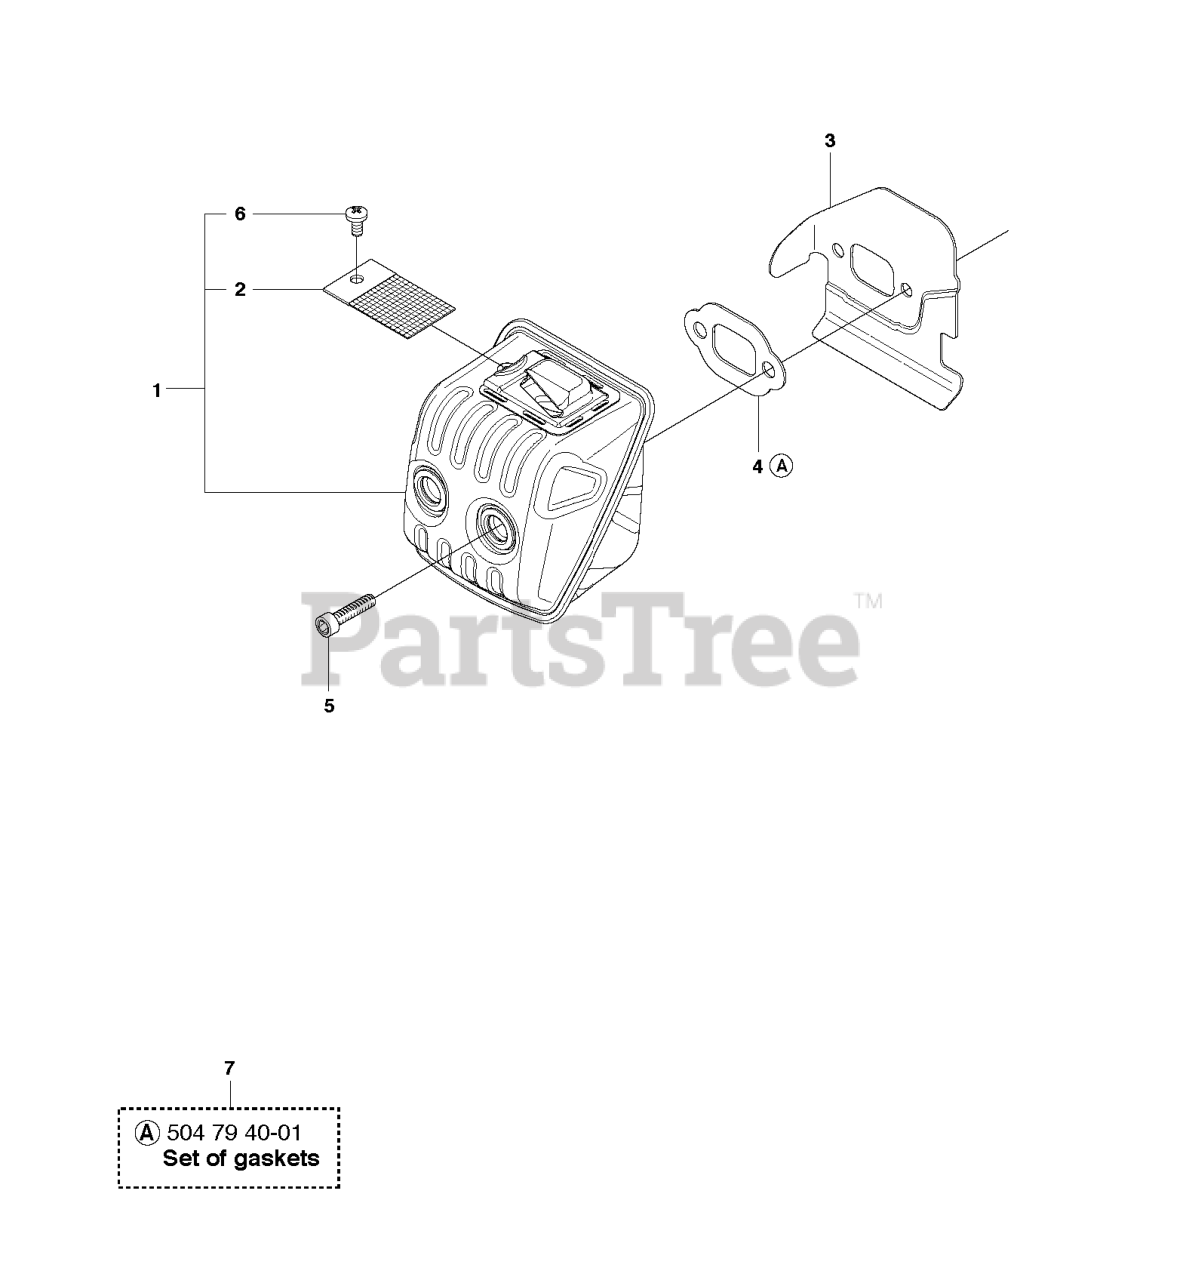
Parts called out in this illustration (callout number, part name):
1	MUFFLER ASSY
2	RP SCREEN
3	HEAT DEFLECTOR
4	RP GASKET
5	SCREW MC6S 6X16
7	GASKET SET
